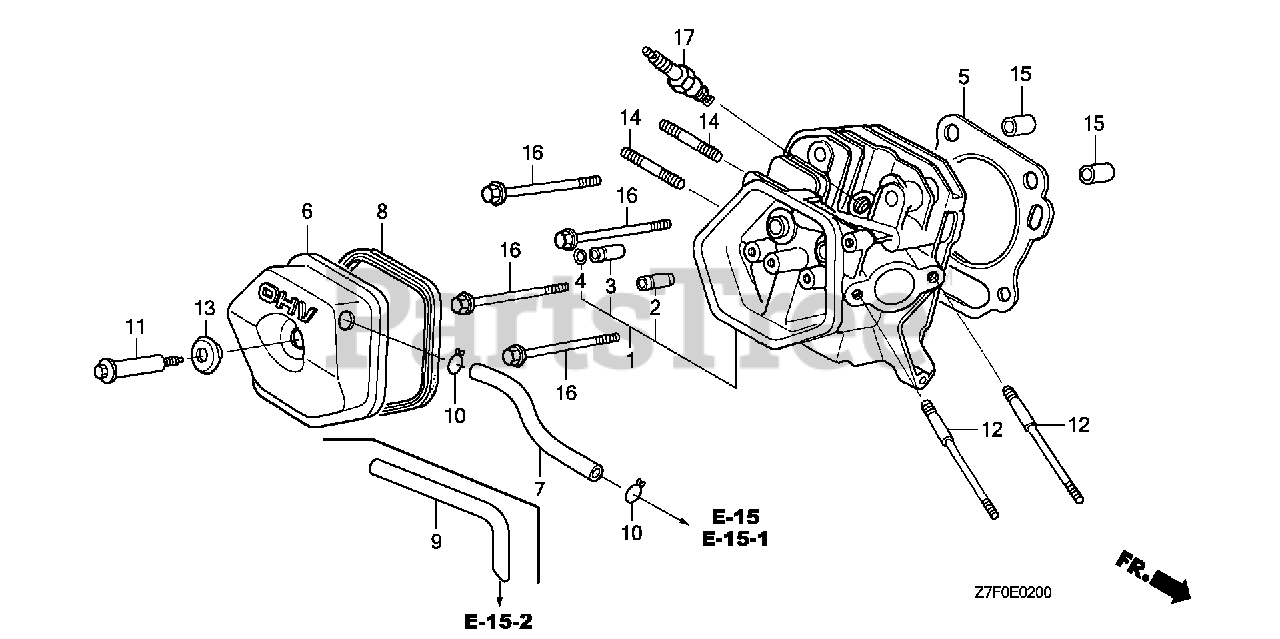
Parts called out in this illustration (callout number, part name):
1	CYLINDER HEAD
2	GUIDE, VALVE (OVER SIZE)
3	GUIDE, EX. VALVE (OVER SIZE)
4	CLIP, VALVE GUIDE
5	GASKET, CYLINDER HEAD
6	COVER, HEAD
7	BULK HOSE, VACUUM (11X1000) (11X105)
8	GASKET, HEAD COVER
11	BOLT, HEAD COVER
12	BOLT, STUD (8X131.5)
13	WASHER, HEAD COVER
14	BOLT, STUD (8X32)
15	PIN, DOWEL (12X20)
16	BOLT, FLANGE (10X80)
17	SPARK PLUG (BPR5ES) (NGK)
17	SPARK PLUG (BPR6ES) (NGK)
